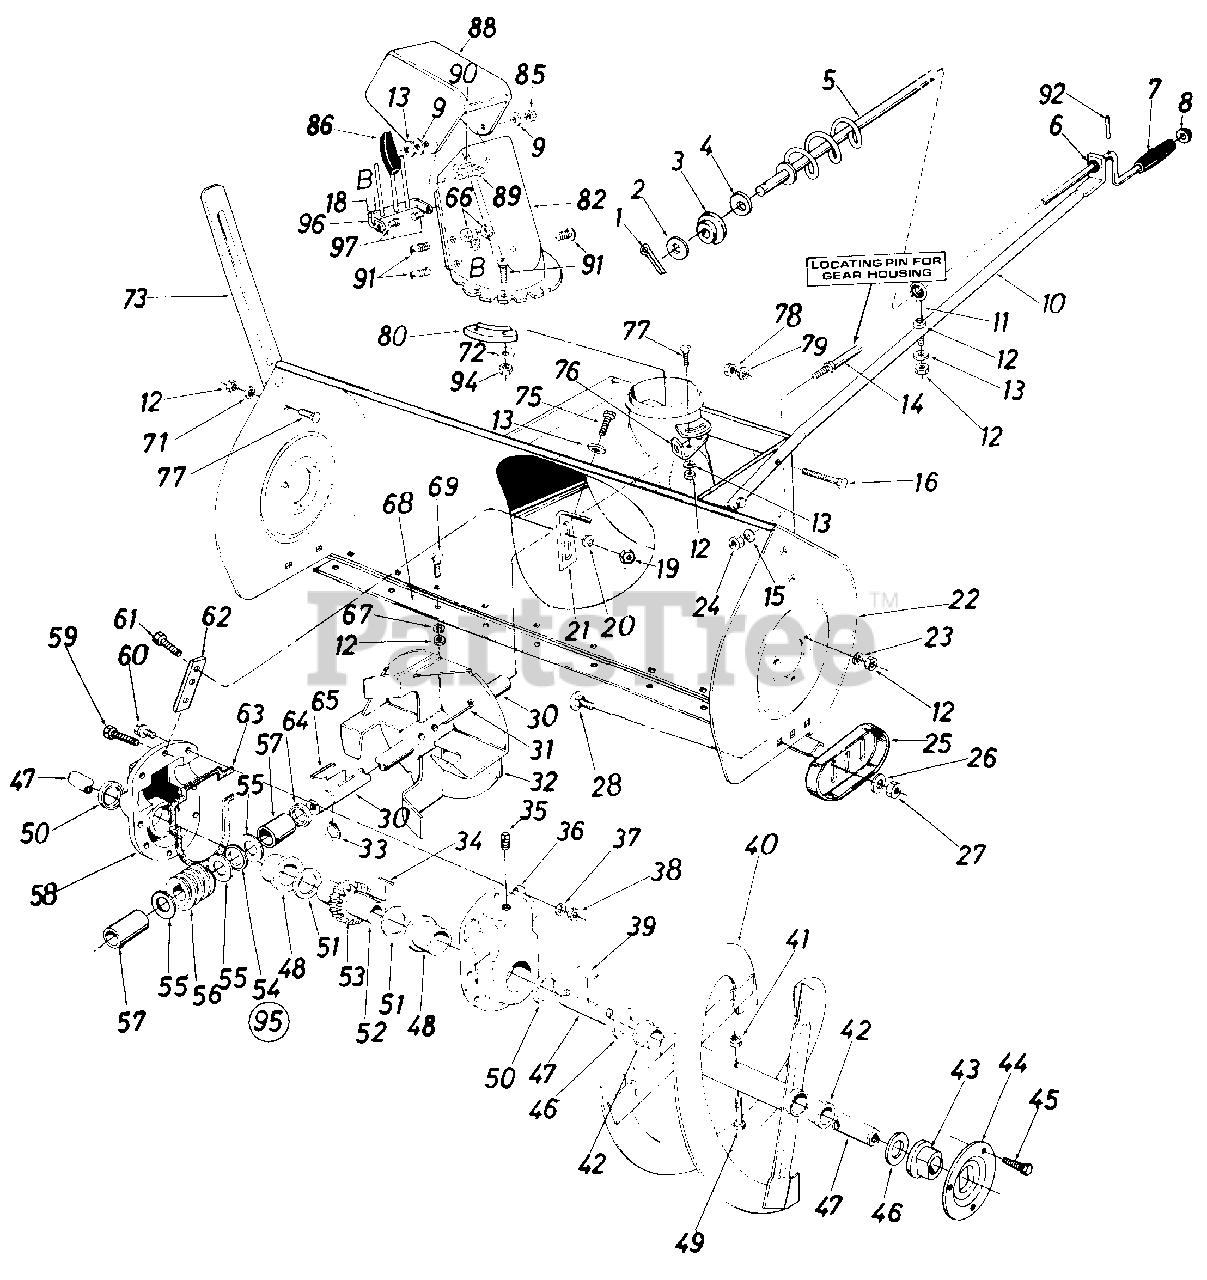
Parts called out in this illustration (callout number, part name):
1	Cotter Pin
2	Fl.-Wash. .39" I.D. x .62" O.D.
3	Plastic Bushing
4	Fl.-Wash. .385" I.D. x .62" O.D.
5	Chute Crank Ass'y.
6	Plastic Bushing
7	Knob (Black)
8	Push Nut 3/8" Rod
9	Fl.-Wash. .344" I.D. x 1.25" O.D.
10	Chute Crank Support Tubing
11	Eyebolt
12	Hex Nut 5/16-18 Thd.*
13	Bell.-Wash. .345" I.D. x .88" O.D.
14	Stud 3/8-16 x 2.75" Lg.
15	Bell.-Wash. .400" I.D. x .88" O.D.
16	Hex Bolt 3/8-24 x 1.25" Lg.*
18	Extension Spring
19	Hex Nut 1/4-28 Thd.
20	Bell.-Wash. .265" I.D. x .75" O.D.
22	45" Snow Blower Housing Ass'y.
23	L.-Wash. 5/16" I.D.*
24	Hex Jam Nut 3/8-16 Thd.
25	Slide Shoe
26	Bell.-Wash. .400" I.D. x .88" O.D.
27	Hex Jam Nut 3/8-16 Thd.
28	Carriage Bolt 3/8-16 x .62" Lg.*
30	Blower Axle .875" Dia. x 14.75" Lg.
31	Spring Pin Spir. 5/16" Dia. x 1.75" Lg.
34	#91 Woodr-Key 1/4 x 3/4" Dia. (HDN)
35	Vent Plug
36	Gear Hsg. Half L.H.
37	Spr.-Wash. .32" I.D. x .62" O.D.
38	Hex Ins. L.-Nut 5/16-18 Thd.
39	#91 Woodr-Key 1/4 x 3/4" Dia. (HDN)
41	Hex Ins. L.-Nut 5/16-18 Thd.
42	Plastic Bushing
43	Flange Brg. w/flats 1" I.D.
44	Bearing Housing
45	Hex Sems Bolt 5/16-18 x .75" Lg.*
46	Fl.-Wash. 1.00" I.D. x 1.75" O.D.
47	Spiral Axle
48	Flange Bearing 1.503" I.D.
49	Shear Bolt 5/16-18 x 1.75" Lg.
50	Oil Seal 1.50" I.D.
51	Fl.-Wash. 1.50" I.D. x 2.00" O.D.
52	Worm Gear Shaft
53	Double Threaded Worm Gear- L. H.
54	Thrust Brg.-.88" I.D. x 1.44" O.D.
55	Fl.-Wash. .88" 1 .D. x 1.4" O.D.
56	Double Threaded Worm-L.H.
57	Sleeve
58	Gear Hsg. Half-R.H.
59	Hex Bolt 5/16-18 x 1.25" Lg.*
60	Hex Bolt 5/16-18 x 1.0" Lg.(Grade 5)
61	Hex Bolt 1/4-28 x .75" Lg.
62	Gear Housing Support Plate
63	Rubber Gasket
64	Oil Seal-.875" I.D.
65	#9 Hi-Pro Key 3/16 x 3/4" Dia. (HT.)
66	Hex L-Nut 1/4-20 Thd.
67	L.-Wash. 5/16" I.D.*
69	Carriage Bolt 5/16-18 x 1.00" Lg.*
71	L-Wash. 5/16" I.D.*
72	Fl.-Wash. 1/4" I.D.
73	Guide Blade
75	Hex Wash. Hd. AB Tap Scr. 5/16" x .75" Lg.
77	Carriage Bolt 5/16-18 x .75" Lg.*
78	Hex Ins. L.-Nut 3/8-24 Thd.
79	L.-Wash. 3/8" I.D.*
80	Chute Flange Keeper
82	Lower Chute
85	Hex Cent. L.-Nut 5/16-18 Thd.
86	Knob Handle
88	Upper Chute
89	Carriage Bolt 5/16-18 x 1.00" Lg.*
90	Truss Mach. Scr. 5/16-18 x .75" Lg.
91	Truss Mach. Scr. 1/4-20 x .75"
92	Roll Pin .12" Dia. x .63"
94	Hex Cent. L-Nut 1/4-20 Thd.
95	Gear Box Ass'y.-Comp.
97	Shld. Nut
